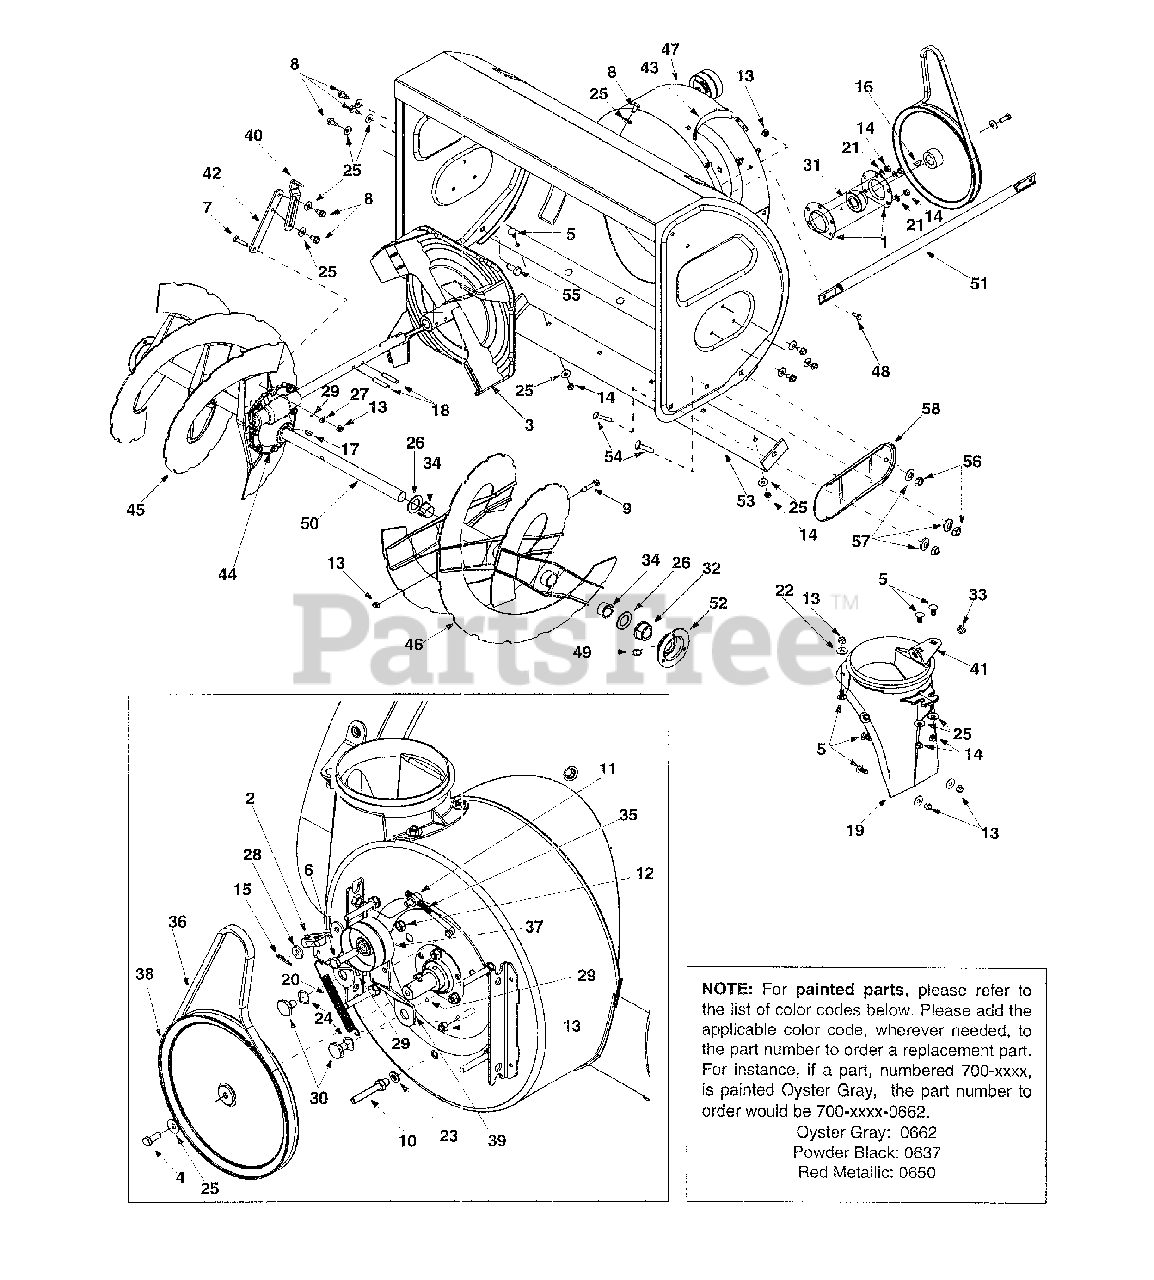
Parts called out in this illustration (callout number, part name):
1	Bearing Housing
2	Bracket Assembly: Auger Break
3	Impeller Assembly: 16"
4	Hex Lock Bolt 5/16-18 x .875"
5	Carriage Bolt 5/16-18 x .750"
6	Hex Screw, Special 3/8-24 x 1.5"
7	Hex Screw 5/16-18 x 1.25"
8	Self-Tapp. Screw 5/16-18 x .625"
9	Shear Bolt 5/16-18 x 1.75"
10	Stud
11	Ferrule
12	Jam Nut 3/8-24
13	Hex Lock Nut 5/16-18
14	Hex Nut 5/16-18
15	Hairpin Clip
16	Key
17	Key
18	Spiral Pin
19	Chute Adapter
20	Extension Spring
21	Lock Washer
22	5/16 Washer
23	Lock Washer
24	Wave Washer
25	Beleville Washer
26	Flat Washer
27	Spring Washer
28	Flat Washer
29	Grease
30	Shoulder Screw
31	Self-Aligning Bearing
32	Flange Bearing w/Flats
33	Plastic Bushing
34	Flange Bushing
35	Idler Rod: Auger
36	V-Belt
37	Flat Idler
38	Pulley
39	Idler Bracket: Auger
40	Support Bracket
41	Chute Crank Bracket
42	Support Plate
43	Chute Bracket
44	Gear Assembly: Auger w/Grease Fitting
49	Lube Fitting
50	Spiral Axle
53	Shave Plate
54	Carriage Screw
55	Carriage Bolt
56	Hex Nut 3/8-16
57	Bell Washer
